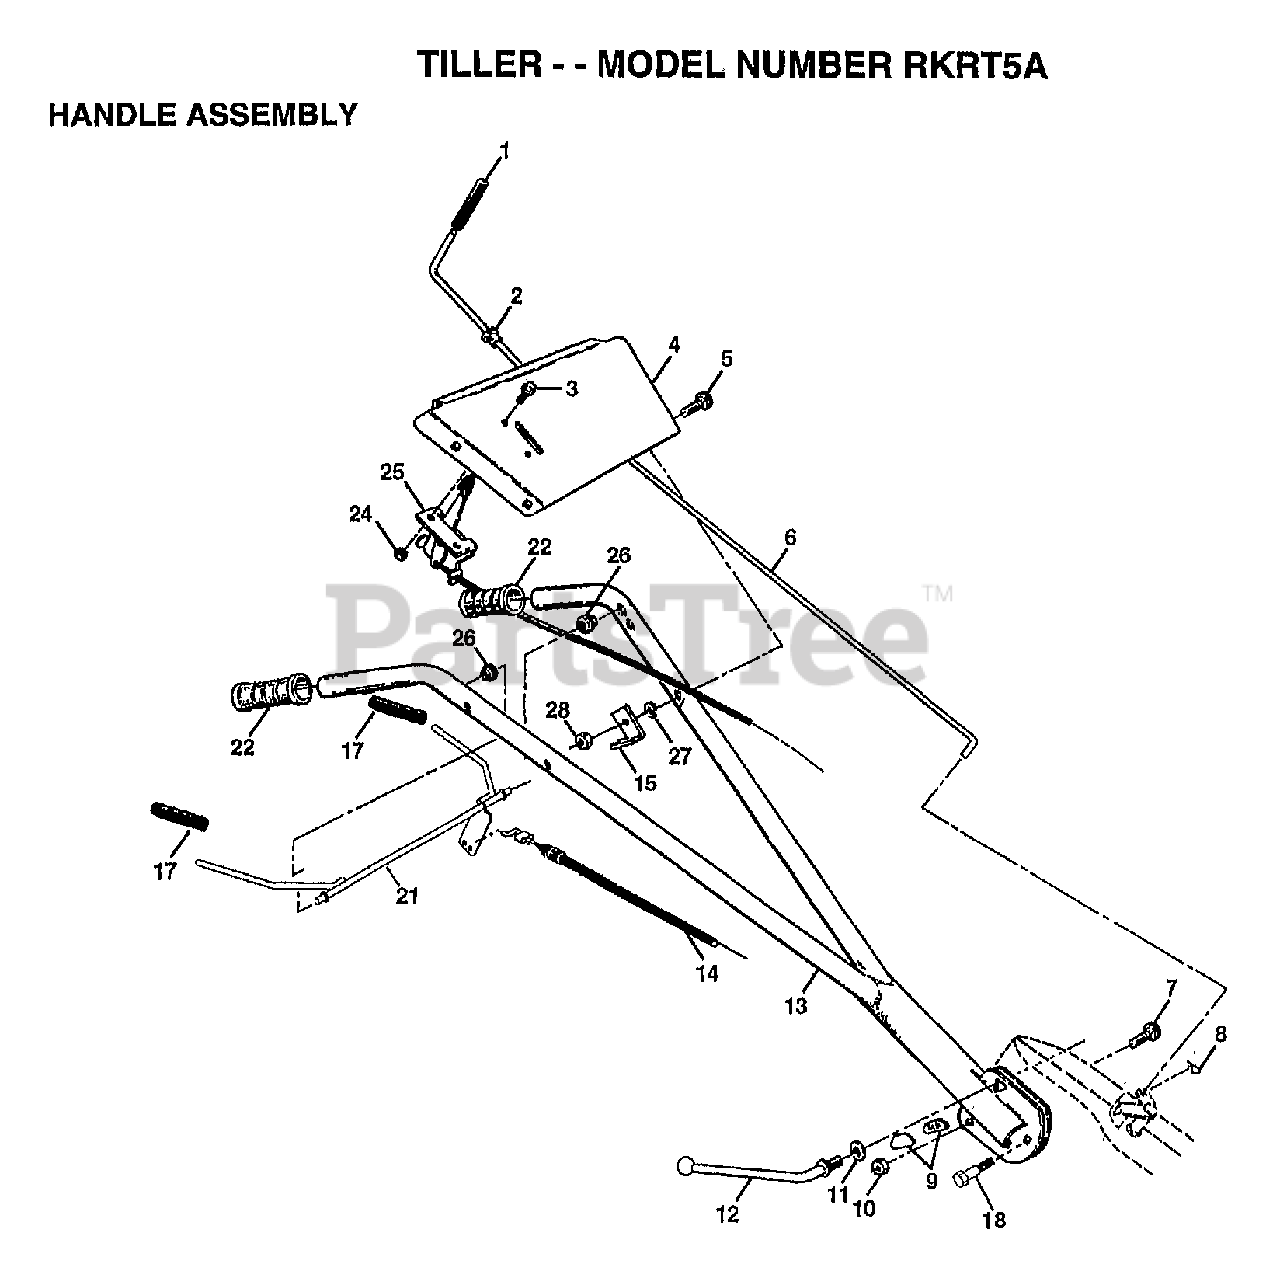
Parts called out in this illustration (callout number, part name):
1	GRIP TI
2	BUSHING
3	SCREW.PNHD.10-24
4	BRACKET, HANDLE
5	BOLT CARRIAGE CRT
6	ROD SHIFT CRT
7	BOLT D
8	RETAINER M
9	LOCK CRT
10	LOCKNUT
11	WASHER CRT
12	LEVER LOCK CRT
14	"CABLE, CLUTCH"
15	BRACKET.CLUTCH.CA
17	GRIP BAR CRT
18	BOLT PIVOT
21	BAR CONTROL
22	"GRIP,HANDLE"
25	"CONT,THROTTLE"
26	GROMMET.HANDLE.V-
27	LOCKWASHER
28	NUT
